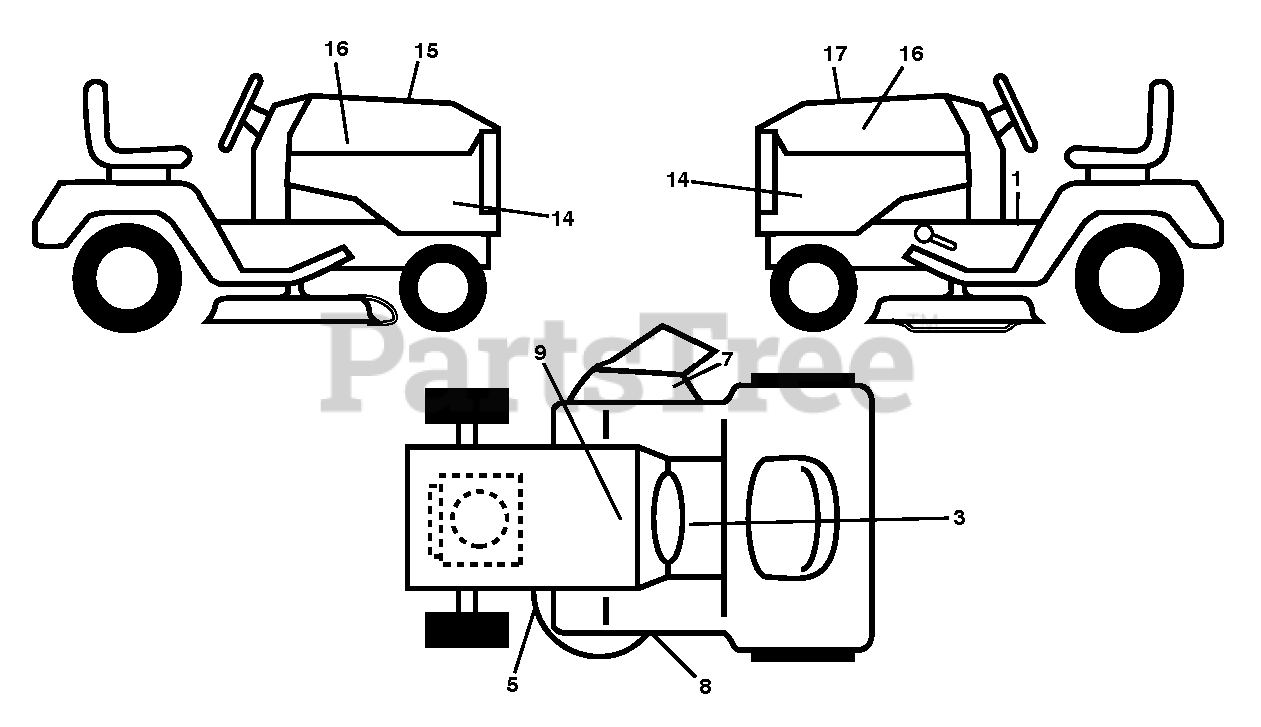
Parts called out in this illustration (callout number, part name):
1	DECAL.WARNING.2007.ENG/FR
3	DCL.WARNING.SPARK.IGNITION.CA
5	DECAL.MOWER.CAUTION.TENSION.AR
7	DECAL.MOWER.WARN.KEEP.HAND.AWY
8	DECAL.MOWER.SCH.48/54.PREM
9	DECAL BTRY SYMBOLS
14	DECAL.SIDE.PANEL.YTH24K48
15	DECAL.WARNING.CUST.RESP.E85.
16	DECAL.BADGE.170MM.TEXTLOGO.
